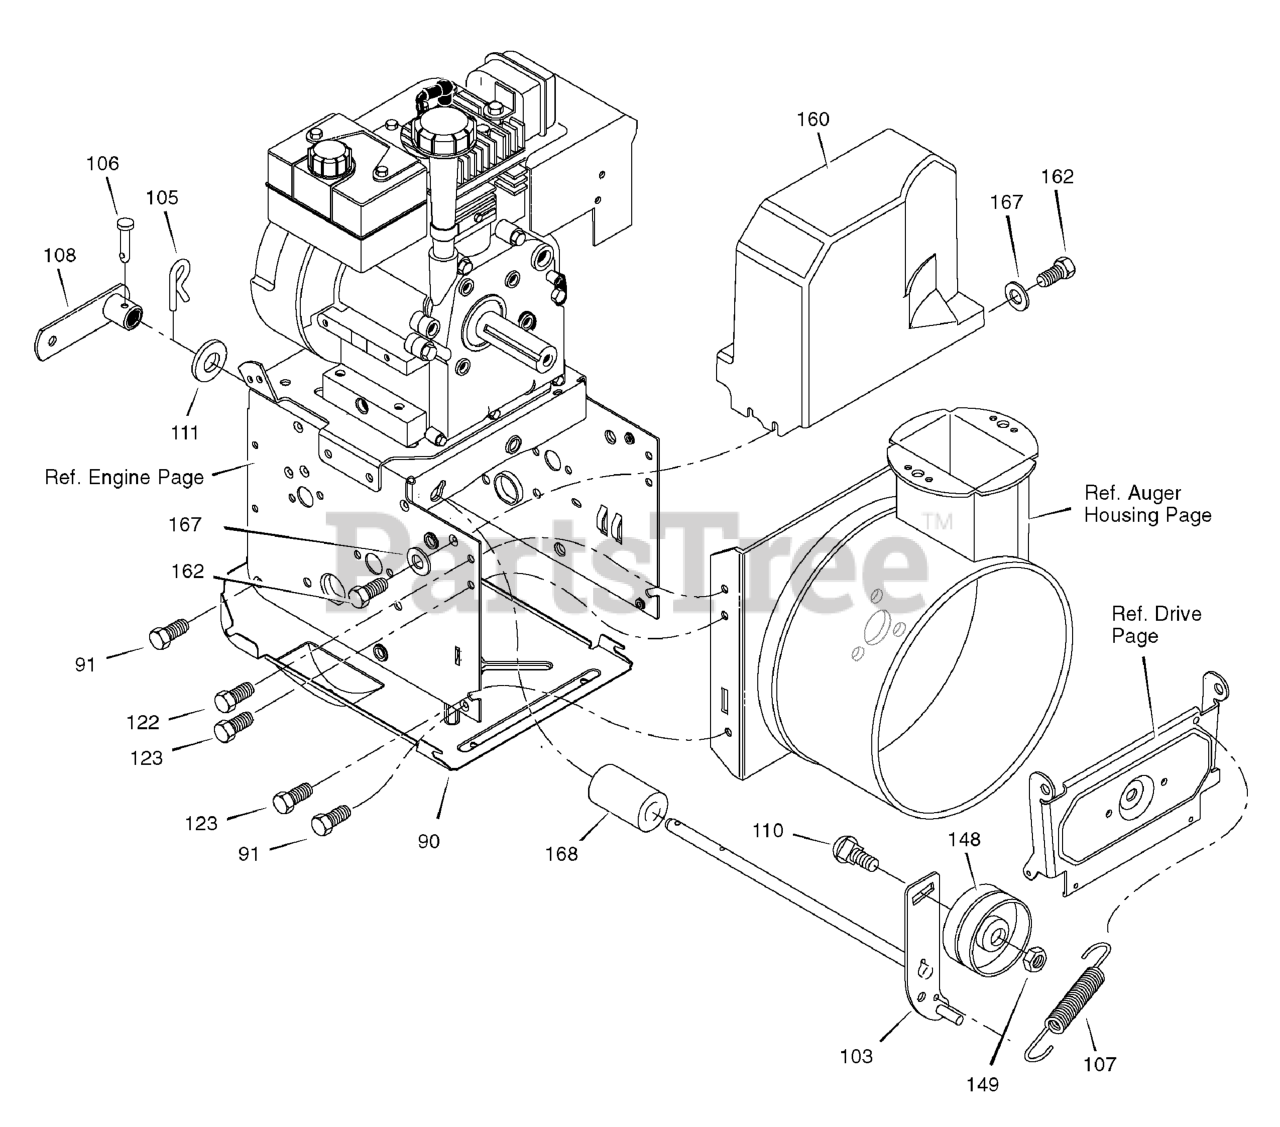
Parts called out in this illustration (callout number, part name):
90	COVER, BOTTOM
91	SCREW, 1/4-20X .63
103	IDLER ASSEMBLY, AUGER
105	PIN, HAIR .38DIAX1.64LG
106	PIN, CLEVIS 3/16" DIA
107	SPRING, TENSION
108	ASSY., SPRING ATTACH
110	BOLT, 3/8-16X1.25 CARR.
111	WASHER, FLAT
122	SCREW, TAP 5/16-18 X .75
123	SCREW, TAP 5/16-18 X .50
148	PULLEY, IDLER
149	NUT, JAM 3/8-16
160	COVER, BELT
162	SCREW, TAP
166	WASHER, FLAT
168	SPACER, AUGER BRACKET
